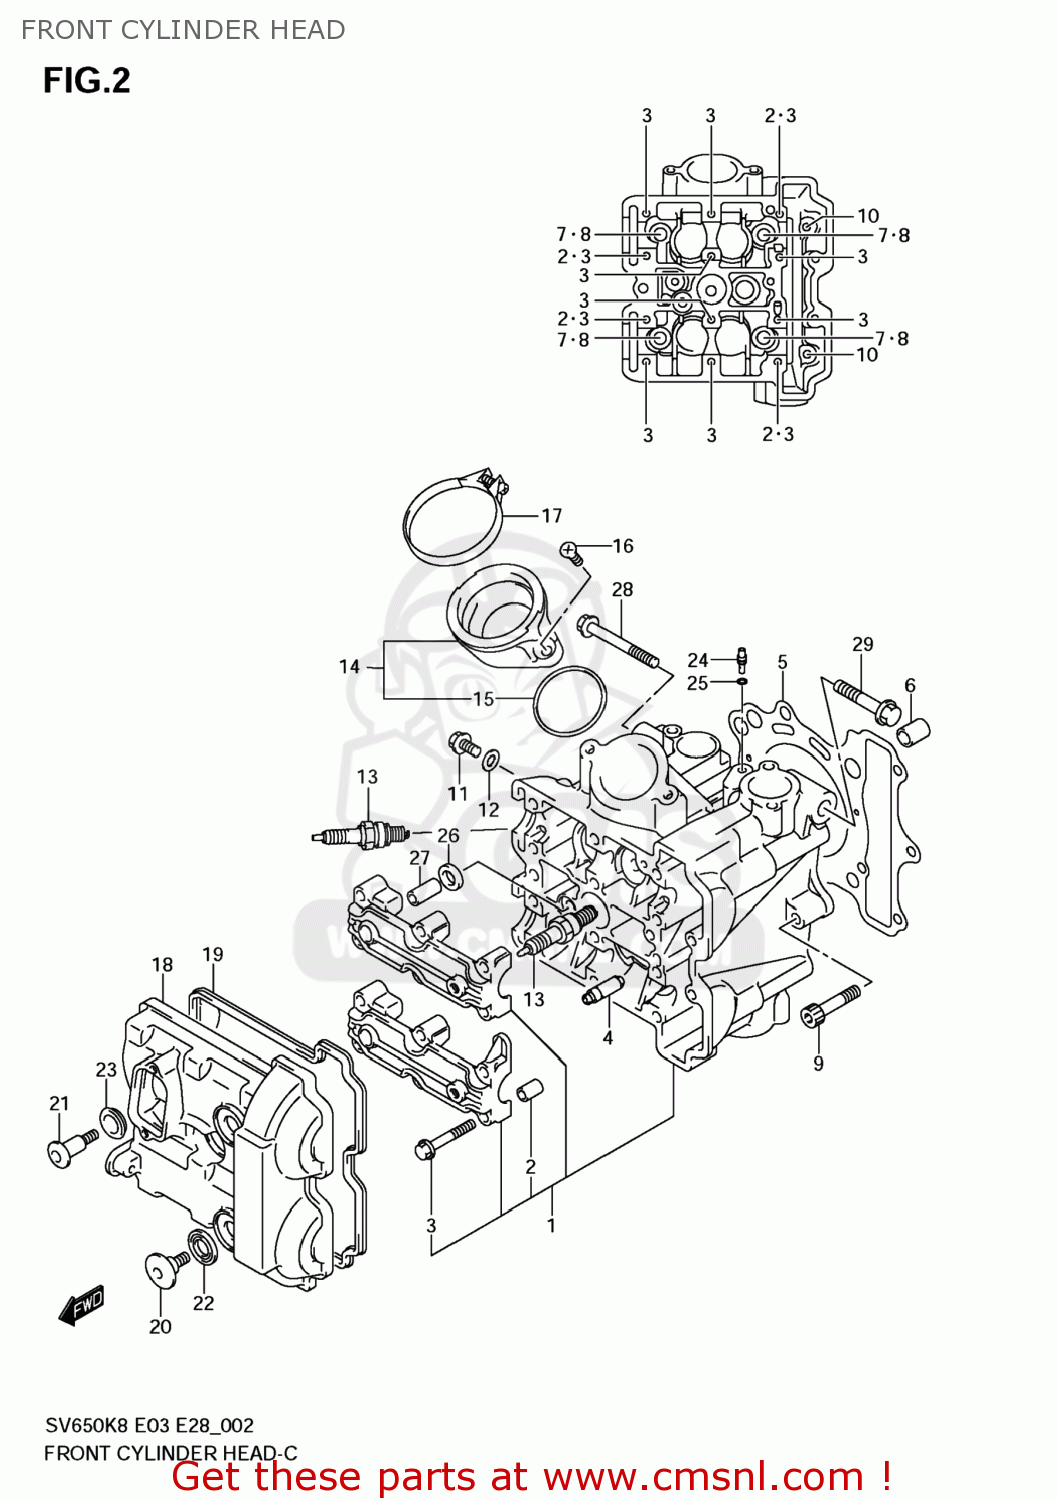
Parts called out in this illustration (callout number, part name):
1	HEAD ASSY,CYLINDER FR
2	PIN(6.2X8X11)
3	BOLT(6X39)
4	GUIDE,VALVE
5	GASKET,CYLINDER HEAD (NAS)
6	PIN
7	WASHER(10.5X19X2)
8	BOLT(10X160)
9	BOLT
10	BOLT(6X70)
11	BOLT
12	GASKET(5.8X13X1.2) (NAS)
13	PLUG,SPARK(CR8E)
14	PIPE ASSY,INTAKE FR
15	O RING(D:2.4,ID:47X42)
16	SCREW
17	CLAMP
18	COVER,CYLINDER HEAD FR
19	GASKET,CYLINDER HEAD COVER (NAS)
20	BOLT(7X17.5)
21	BOLT(7X31)
22	WASHER,CYL HEAD COVER
23	CUSHION,HEAD COVER BOLT
24	JET(8)
25	O RING(D:1.2,ID:4)
26	GASKET,2ND AIR PASSAGE (NAS)
27	PIN(6.2X8X16)
28	BOLT(10X105)
29	BOLT
